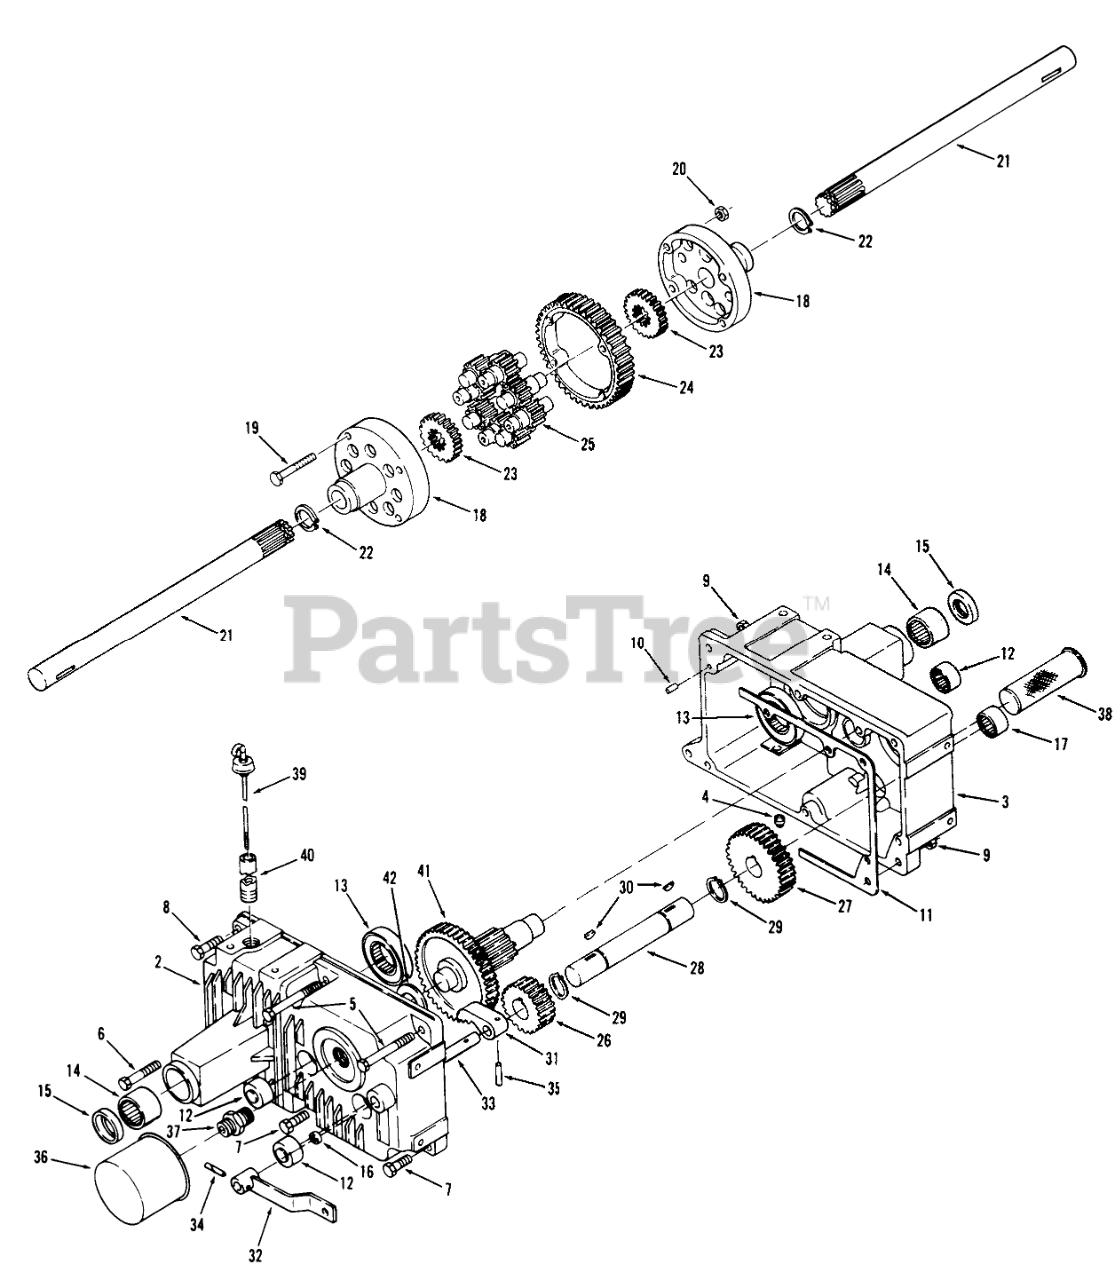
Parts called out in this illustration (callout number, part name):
1	Assy-Transaxle
2	RH TRANSMISSION CASE
3	Case LH
4	PLUG 1/4 PIPE ALLEN
5	H H C S
6	HHCS
7	Bolt
8	Bolt
9	Nut
10	PIN-DOWEL
11	GASKET
12	BEARING-NEEDLE
13	BALL BRG 1 1/2 I.D.
14	Bearing-Axle
15	SEAL-OIL
16	SEAL BRAKE SHAFT
17	Needle Bearing
18	DIFFERENTIAL END CAP
19	BOLT-HEX
20	NUT
21	AXLE-REAR
22	RING-SNAP
23	GEAR-AXLE DIFFERENTIAL
24	GEAR-DIFFERENTIAL RING, 43T
25	GEAR-PINION, 11T
26	GEAR 24T
27	Gear 44T
28	SHAFT GEAR
29	Snap Ring
30	Key
31	PAWL PARKING
32	Brake Lever
33	Shaft
34	Pin-Roll
35	PIN-ROLL
36	Filter
37	FITTING
38	Strainer
39	Dipstick
40	Nipple
41	GEAR ASSY
42	WASHER-THRUST
